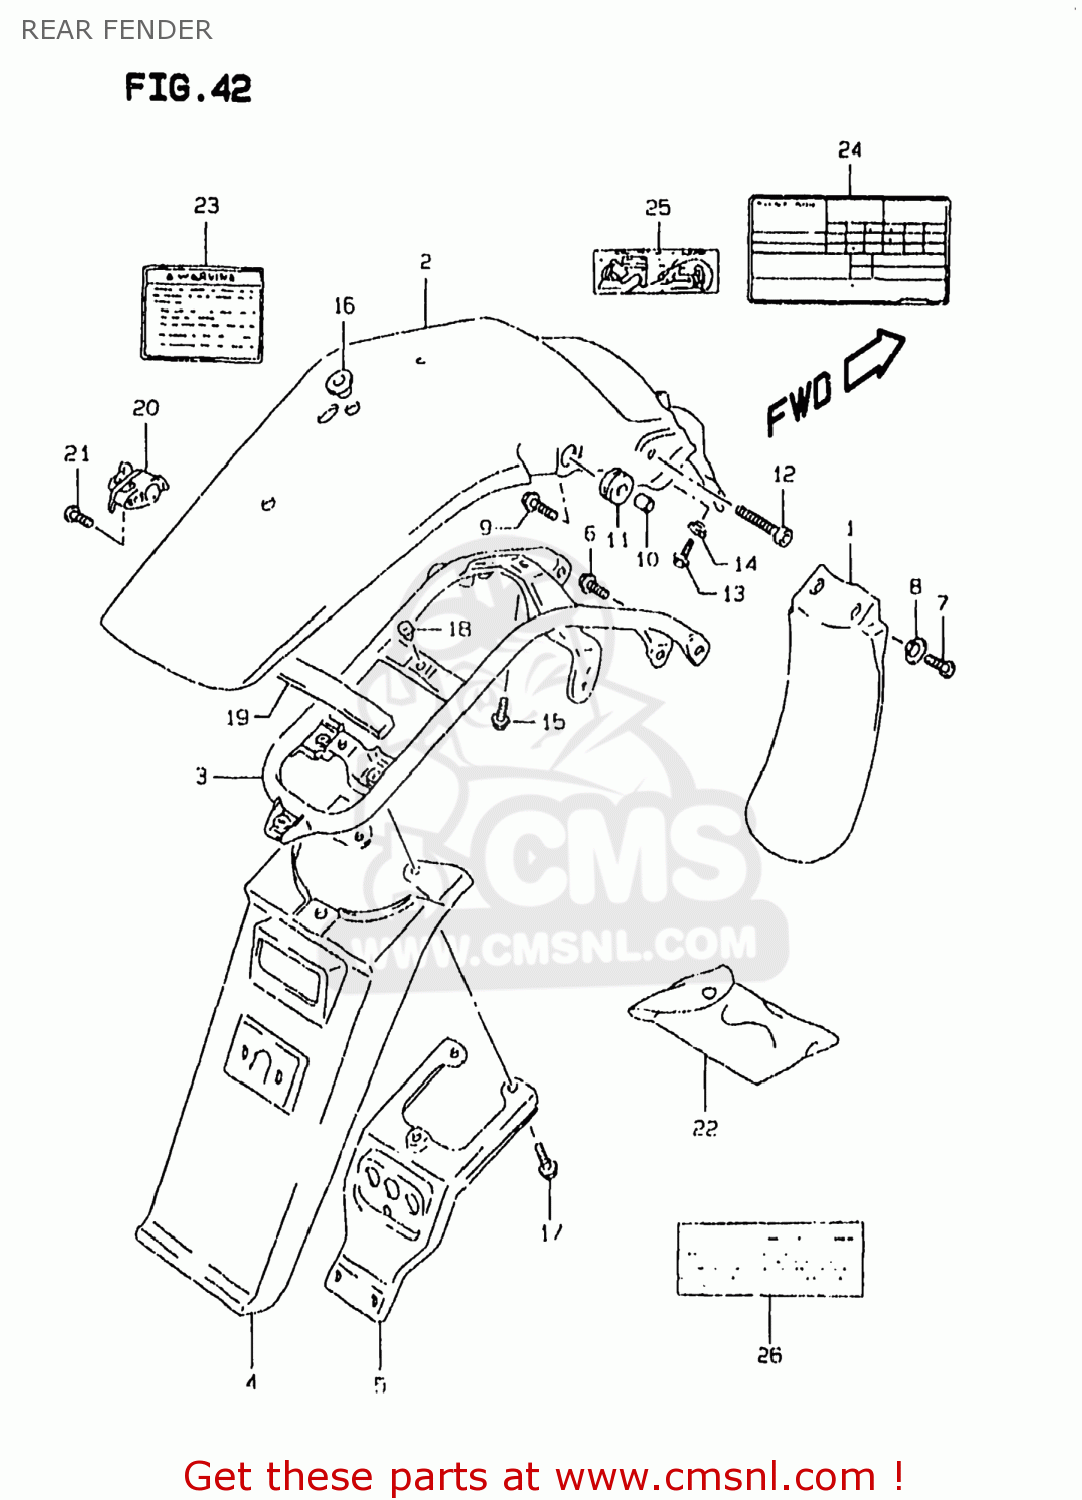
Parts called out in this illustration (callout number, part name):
1	BODY,RR FENDER FR
2	BODY,RR FENDER RR
3	REINF,RR FENDER
4	EXTENSION,RR FENDER
5	REINFORCEMENT,RR FENDER EXT
6	BOLT 8X12
7	SCREW 6X12
8	WASHER
9	BOLT(8X30)
10	SPACER(8.5X12X7)
11	CUSHION
12	BOLT(8X30)
13	BOLT
14	WASHER
15	BOLT
16	WASHER(14.2X26X1.2)
17	BOLT
18	CUSHION
19	CUSHION(25X185X15)
20	LOCK SET,HELMET
21	SCREW
22	TOOL ASSY
23	LABEL,WARNING SAFETY
24	LABEL (TIRE INFORMATION)
25	LABEL,PIPING DIAG
26	LABEL (MANUAL NOTICE)
27	MANUAL, OWNER'S
